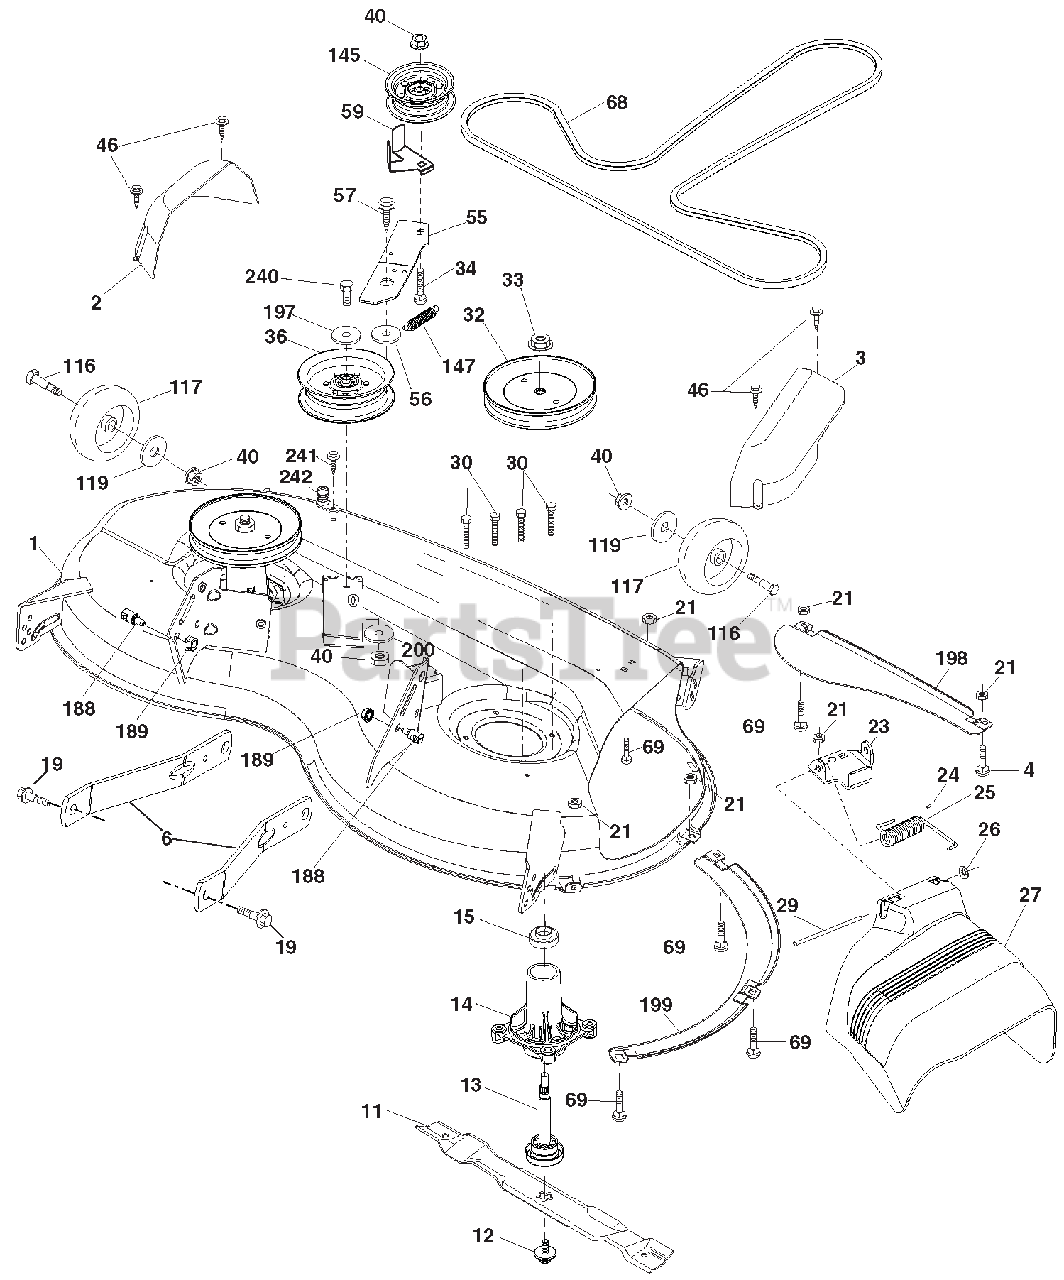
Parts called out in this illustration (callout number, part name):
1	MOWER HOUSING
2	COVER.MANDREL.LH.46"
3	COVER.MANDREL.RH.46"
4	BOLT.HEX.HD.1/4-20UNC X 3/4
6	ARM.SUSPENSION.MOWER.REAR.LD
11	BLADE.MOWER.46"HI LIFT BAGGER
12	SCREW 7/16-20 X 1
13	SHAFT ASM
14	HOUSING.MANDREL.4PT.SERVICE
15	BEARING
19	BOLT.SHOULDER
21	Nut, Hex, Crownlock 5/16-18
23	BRACKET.DEFLECTOR.38/42"2005
24	CAP.SLEEVE..80X.112.BLK.MOWER
25	SPRING.TORSION.DFL.38/42/46.GR
26	NUT.PUSH.PHOS.& OIL
27	SHIELD.DEFLECTOR.MOWER 46"BLK
29	ROD.HINGE.42/46"
30	SCREW.THD ROLL.DOD PT.HEX
32	PULLEY.MANDREL.5.438 PD.42"
32	MANDREL ASM
33	NUT.FLANGE.LOCK.TOP
34	BOLT.CARR.SH.3/8-16X1-1/2.GR5
36	PULLEY.IDLER.4.50.RAW
40	Nut, Hex, Flangelock 3/8-16
46	SCREW.THD.ROLL.1/4-20 X 5/8
55	IDLER.ARM
56	SPACER.RETAINER
57	SCREW.3/8-16X1.SMGML.TAP/R.BLK
59	GUARD.TUV.IDLER
68	V-BELT.DRIVE.MWR.MECHANICL.46"
69	BOLT.5/16-18HEX.WHS.HD.LCKSERR
116	BOLD SHLD "A" 2.41 "B" 1.66
117	WHEEL.GAGE.HALF.SPOKED
119	Washer 3/8 x 7/8 x 14 Ga.
145	PULLEY.IDLER 48"PRIMARY
188	STUD.FASTNER.W/'D'ANTI-ROTATIO
189	Nut, Lock Hex Flange 5/16-18 u
197	Washer 13/32 x 13/16 x 12 Ga.
198	BAFFLE.CENTER.FRONT
199	BAFFLE.FRONT.RH
200	WASHER.13/32 X 1 X 1/2.11GAHRD
240	BOLT.FIN.HEX.3/8-16X 2-1/4 GR5
242	PORT WASHOUT
244	REPLACEMENT MOWER, COMPLETE
